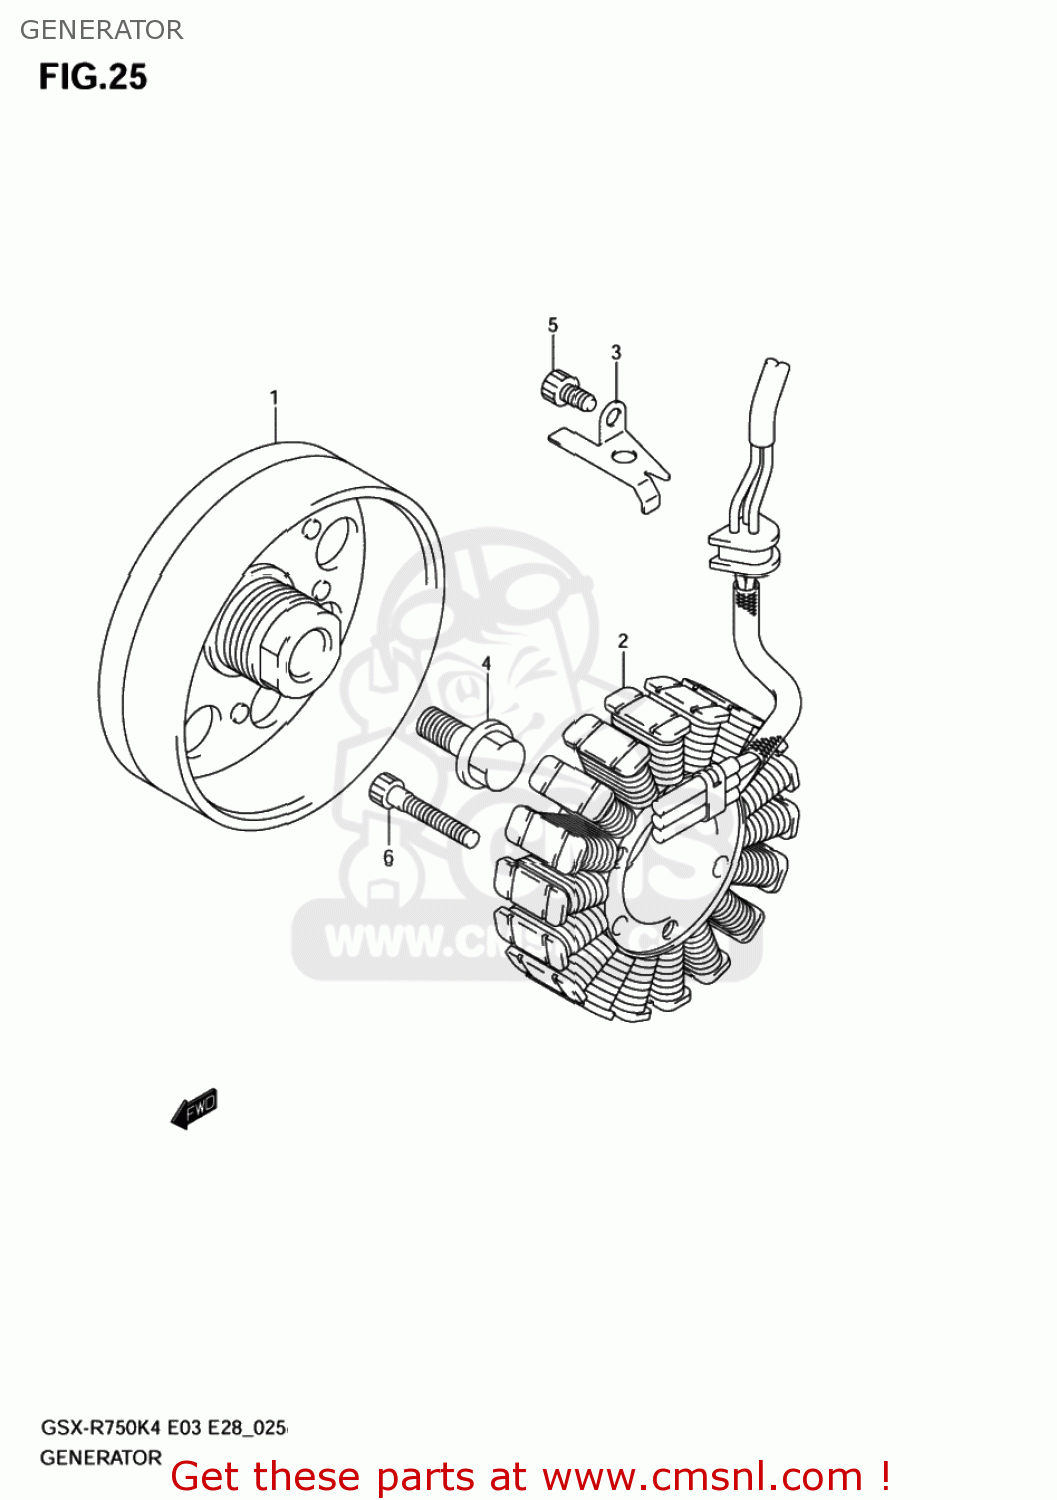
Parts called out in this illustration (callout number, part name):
1	ROTOR ASSY
2	STARTER ASSY
3	CLAMP,MAGNETO LEAD
4	BOLT(12X23)
5	BOLT,STRANGER
6	BOLT
